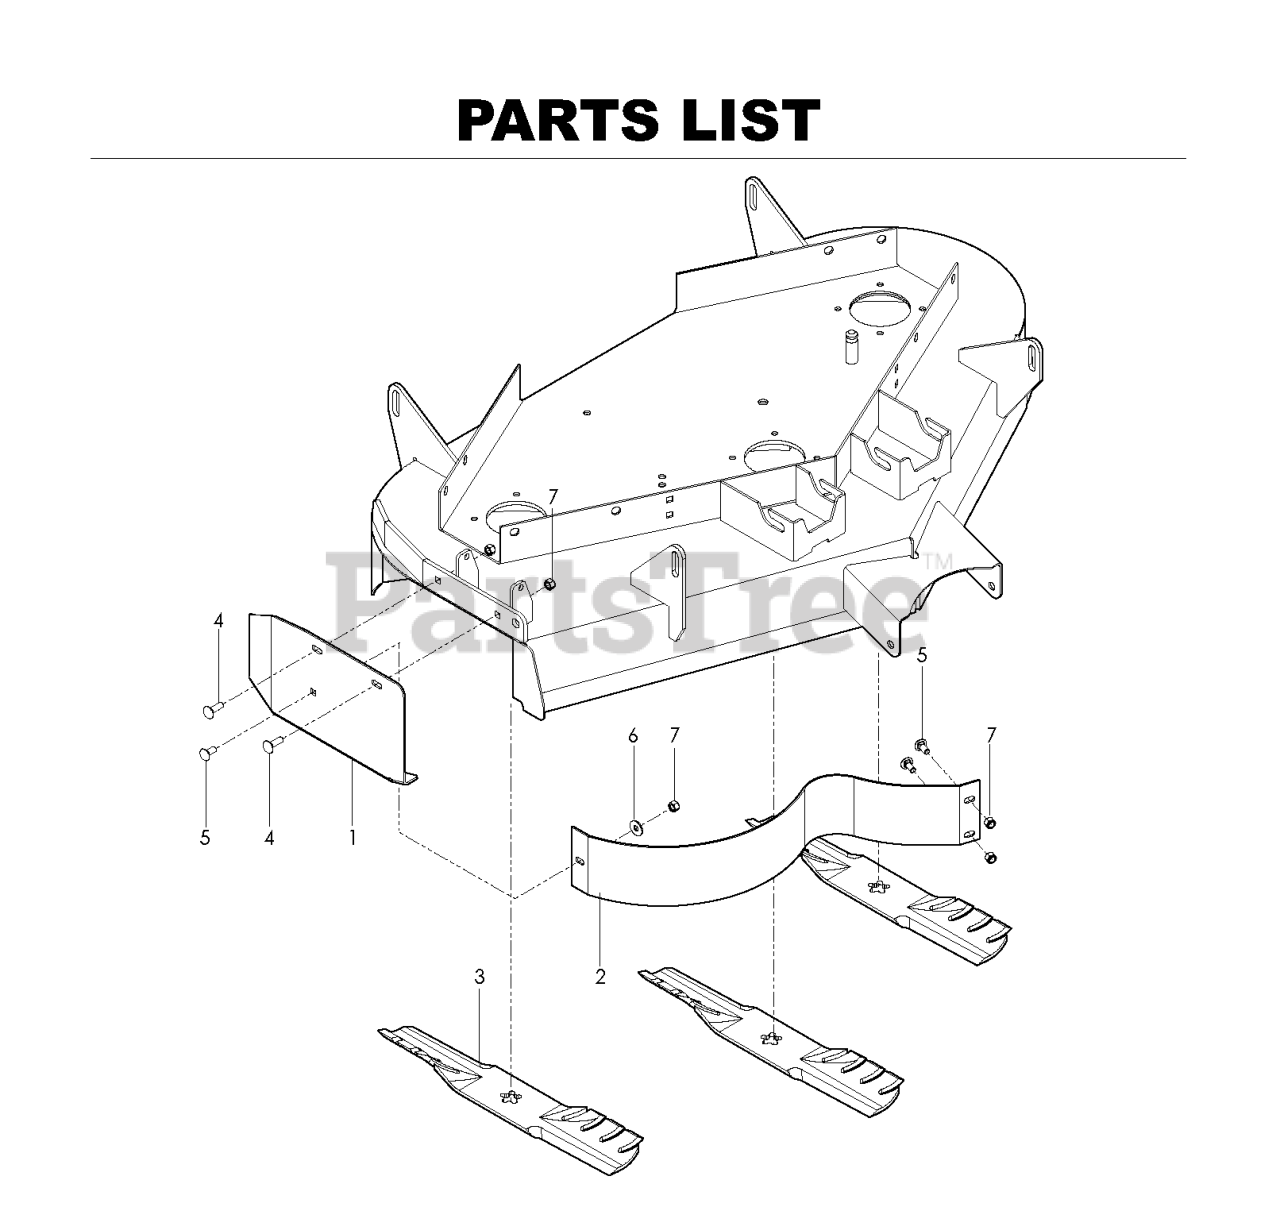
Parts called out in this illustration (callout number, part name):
1	MULCH CAP 42 - PAINTED
2	MULCH BAFFEL 42" - PAINTED
3	BLADE, GATOR 42 (14-5/8")
4	RHSNB 5/16C X 1
5	BOLT 5/16C X 3/4" CARRIAGE
6	WASHER 5/16 FLAT
7	NUT 5/16 NYLOC
